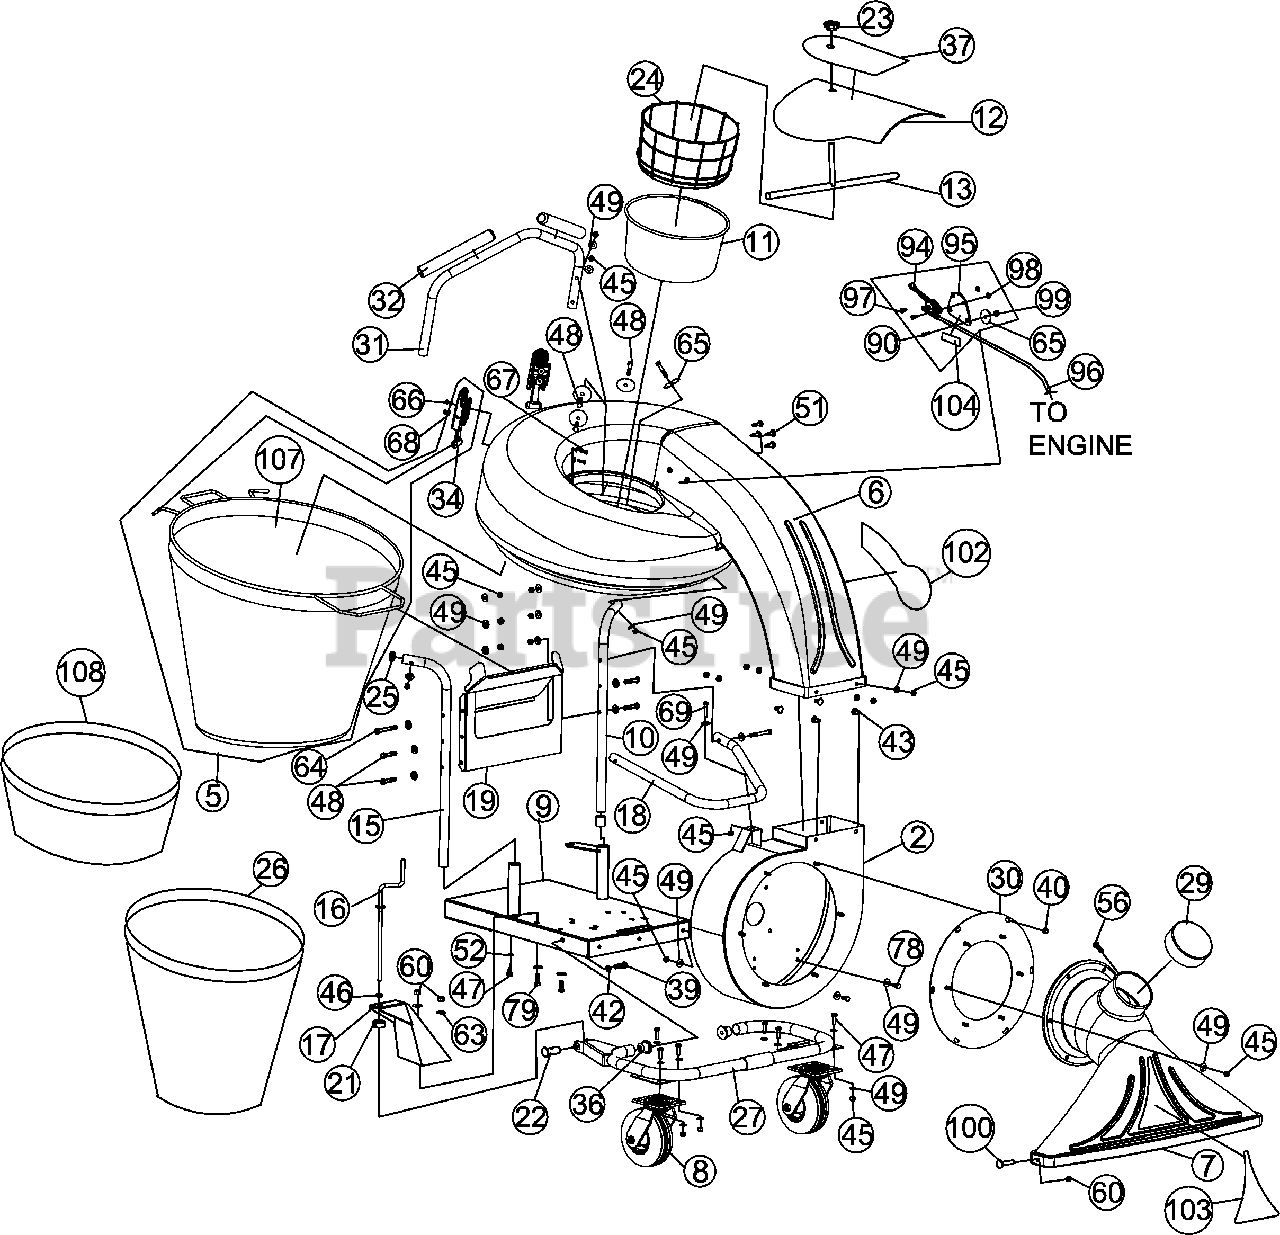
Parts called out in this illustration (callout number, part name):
2	HOUSING QV WA W/LABELS
7	NOZZLE 32" W/LABELS
8	CASTER SWIVEL QV
9	ENGINE BASE 5 HP WA SP
10	HANDLE LOWER LFT
11	HOOD FILTER
12	HOOD SCOOP QV PUSH W/LABEL
13	ROD FILTER HOLDER QV
15	HANDLE LOWER RT
16	HEIGHT ADJ ROD
17	HEIGHT ADJ BRACKET WA
18	HANDLE WISHBONE
19	BRACKET HANDLE SUPPORT
21	STOP COLLAR
22	PIVOT HEIGHT ADJ QV
23	KNOB 3/8" - 16 SOLID HUB
24	FILTER FRAME
25	PLUG TUBE INSERT 1" OD
26	DUST SOCK
27	FRAME CASTER QV WA
28	INSERT 5/16"-18 TUBE 14/16 GA
29	CAP 5" VINYL BLACK
30	PLATE NOZZLE WA QV
31	HANDLE UPPER QV
32	GRIP 1" OD X 9.5"
34	BAG LATCH
36	BUSHING FRAME PIVOT
37	LABEL INSTRUCTION QV
39	SCREWCAP 3/8"-16 X 1 1/4" HCS ZP
40	NUT 5/16-18 SER HEX WSHR FLNG ZP
42	WASHER LOCK 3/8" ST MED
43	BOLT CARRIAGE 5/16"-18 X 3/4" ZP
45	NUT LOCK 5/16"-18 HEX ZP
46	BUSING HEIGHT ADJ BRKT QV
47	SCREWCAP 5/16"-18 X 1" HCS ZP
48	SCREWCAP 5/16"-18 X 1 3/4" HCS ZP
49	WASHER 5/16" FLAT
51	PLUG SNAP RIVET 0.232 DIA
52	WASHER LOCK 5/16" SPLIT
56	SCREW PLASTITE 1/4"-20 X 3/4" HWH ZP
60	NUT LOCK 3/8" -16 HEX
63	WASHER 3/8" FLAT
64	SCREWCAP 5/16"-18 2 3/4" HCS ZP
65	WASHER 2" OD X 0.344 ID X 16 GA
66	NUT LOCK #10-24 HEX
67	SCREW MACH #10-24 X 3/4"
68	WASHER #10 SAE
69	SCREWCAP 5/16"-18 X 1 1/2"
78	SCREWCAP 5/16"-18 X 3/4" HCS ZP
79	SCREWCAP 3/8"-16 X 1" HCS ZP
90	SCREWCAP 1/4"-20 X 3/4"
94	CONTROL THROTTLE
95	PLATE THROTTLE
96	CABLE THROTTLE
97	SCREW MACH HD PHIL #10-24
98	NUT LOCK LT #10-24
99	NUT FLANGE 1/4"-20
100	BOLT CARRIAGE 3/8"-16 X 1"
102	LABEL BADGING QV
103	LABEL NOZZLE QV
104	LABEL THROTTLE
107	BAG NO CLASPS SERVICE KIT
108	DUST SKIRT
